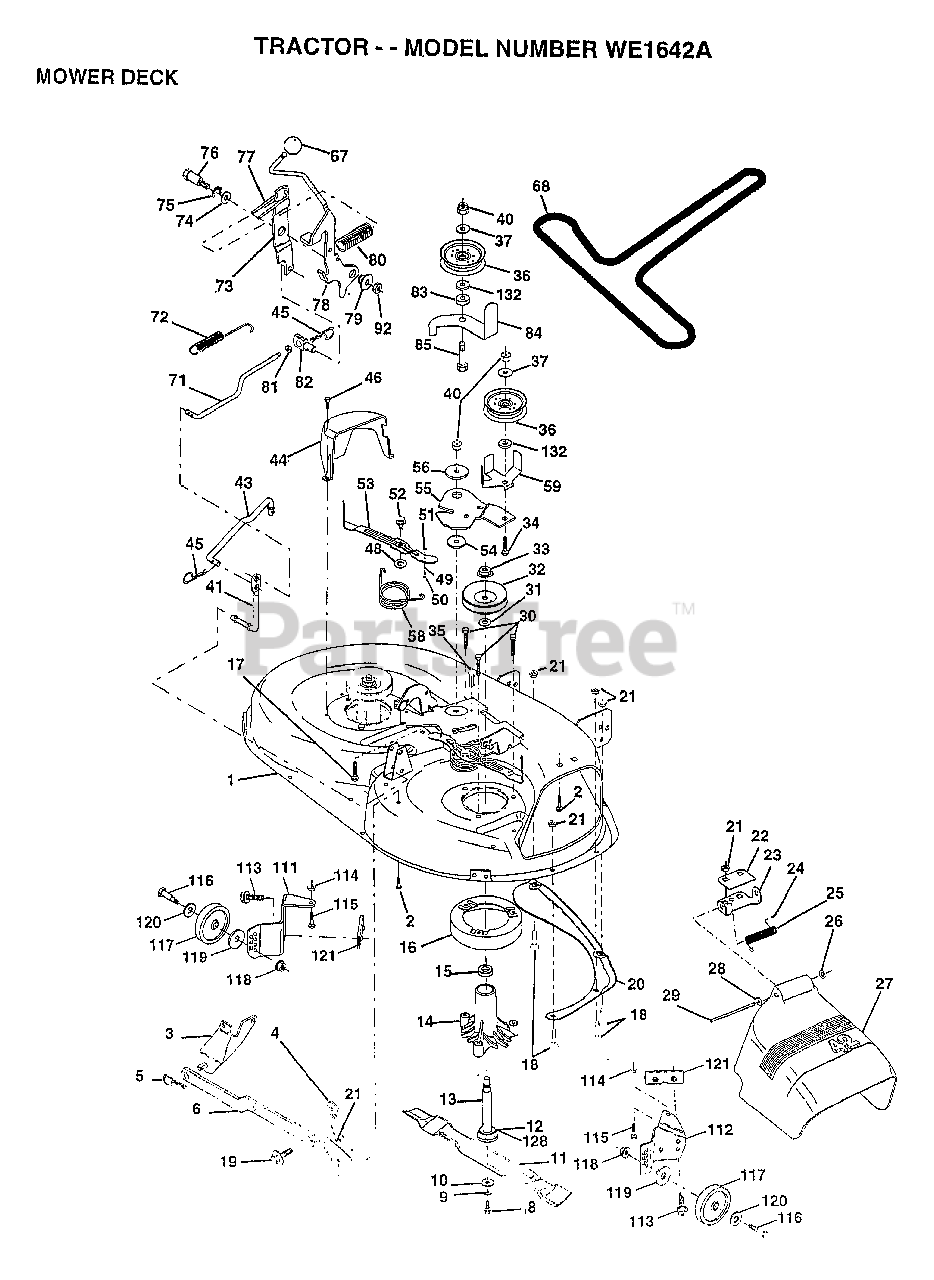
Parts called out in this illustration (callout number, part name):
1	DECK.WELD.42.
2	BOLT
3	BRKT ASM SWAY BAR
4	BRKT DECK SW BAR
8	BLADE BOLT
10	WASHER.HARD.BLADE
11	"BLADE.42"" HIPERF"
12	BEARING.BALL
14	HSG ASM MANDREL
15	BEARING
16	STRIPPER RND MWR
17	BOLT RDHD 3/8-16
18	BOLT
19	BOLT SHD 5/16-18
22	STIFFENER BRKT
23	DEFLECTOR BRKT
24	CAP-SLEEVE LT
25	SPRING TORSION
26	NUT PUSH M
27	DEFLECTOR.SHIELD
28	WASHER
29	HINGE ROD
31	WASHER
32	PULLEY.MANDREL.42
34	BOLT
35	XMAS TREE FASTNER
36	FLAT IDLER PULLEY
37	WASHER
41	PIVOT ROD
43	ROD CLUTCH W/NIBS
44	GUARD MAND LH BLK
45	RETAINER M
46	SCREW.1/4-20X5/8
48	HARD SMALL WASHER
49	ROLLER ASM-CAM
50	SHOULDER BOLT
51	LOCKNUT
52	BOLT.SHLD.5/16-18
54	HARDENED WASHER
55	ARM-IDLER
56	SPACER RETAINER
58	SPRING TORSN BRAK
59	GUARD IDLER TUV
67	KNOB T(3/8 HOLE)
68	BELT.V.T-PATH
71	ROD CLUTCH 38/42
72	RETURN SPRING
73	CLUTCH ARM SECOND
74	WASHER
75	RING
76	SHOULDER BOLT
77	SPRING KEEPER
78	LEVER ASM-CLUTCH
79	BUSHING
80	SPRING.CLUTCH.MWR
81	NUT
82	TRUNION ADJ
83	WASHER
84	"KEEPER-BELT,FIXED"
85	BOLT RDHD 3/8-16
92	NUT
111	BRACKET.GWHL.LH.
112	BRACKET.GWHL.RH.
113	SCREW
116	BOLT M
117	WHEEL.GAGE.BLK.PL
118	LOCKNUT
119	WASHER
120	WASHER
121	BRACKET.EXTRD.GWL
128	WASHER.FELT.
132	WASHER GT
